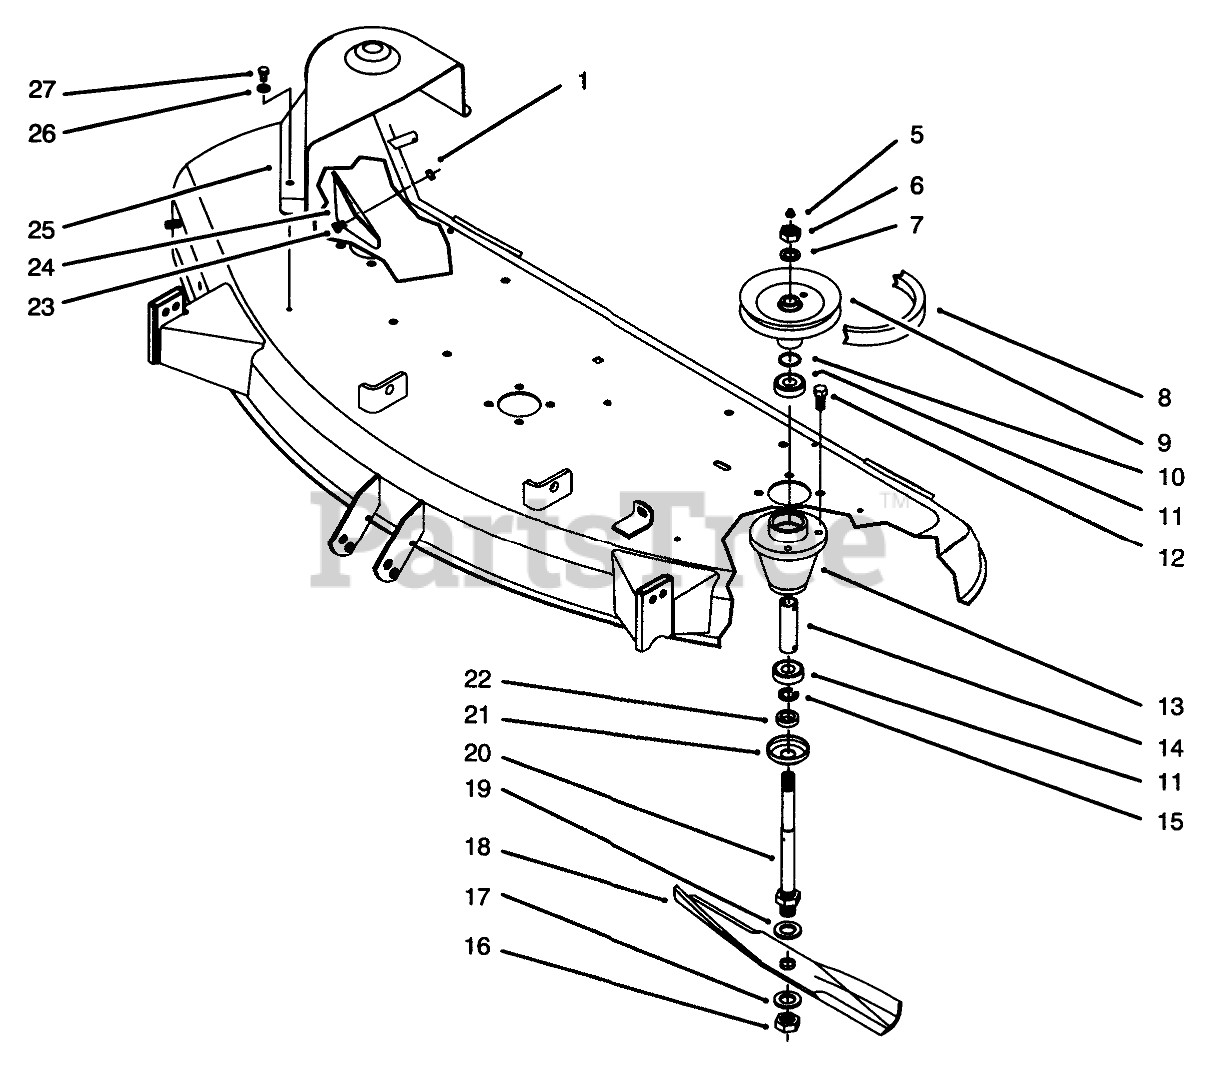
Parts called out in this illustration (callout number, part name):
1	NUT-LOCK, NI
5	FITTING-GREASE
6	NUT-JAM
7	WASHER-LOCK
8	Belt-V
9	PULLEY
10	O RING
11	BEARING-BALL
12	SCREW-HH
13	HOUSING-SPINDLE
15	RING-RETAINING
16	NUT-JAM
17	WASHER-FLAT
18	BLADE KIT (3 PACK)
19	WASHER-FLAT
20	SHAFT-SPINDLE
21	CUP-SPINDLE
22	SPACER-BLADE
23	SCREW-HH
24	GUARD-CHUTE RED
25	COVER-BELT, RH
26	WASHER-FLAT
27	SCREW-HWH
